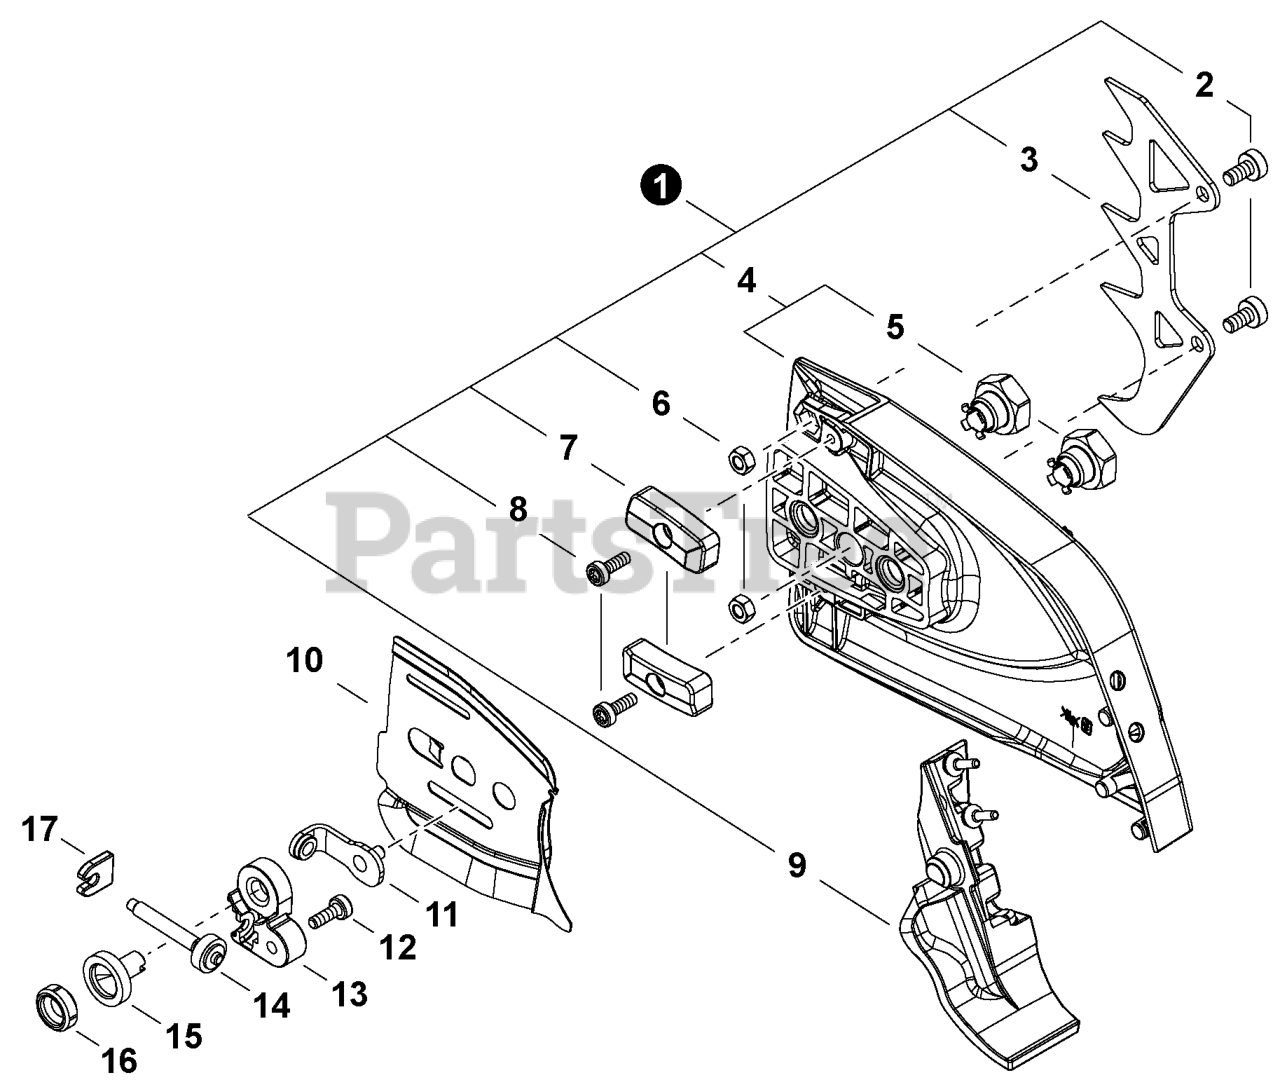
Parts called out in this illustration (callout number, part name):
1	SPROCKET GUARD ASSY
2	BOLT, TORX 5x10
3	SPIKE, BUMPER
4	GUARD, SPROCKET
6	NUT, LOCK M5
7	PLATE, FRICTION
8	BOLT, TORX 4x12
9	CUSHION
10	PLATE, GUIDE - INNER
11	TENSIONER, CHAIN
12	BOLT, TORX 4x12
13	COLLAR 8
15	GEAR, WORM
16	COLLAR 10
17	GUIDE, SHAFT
